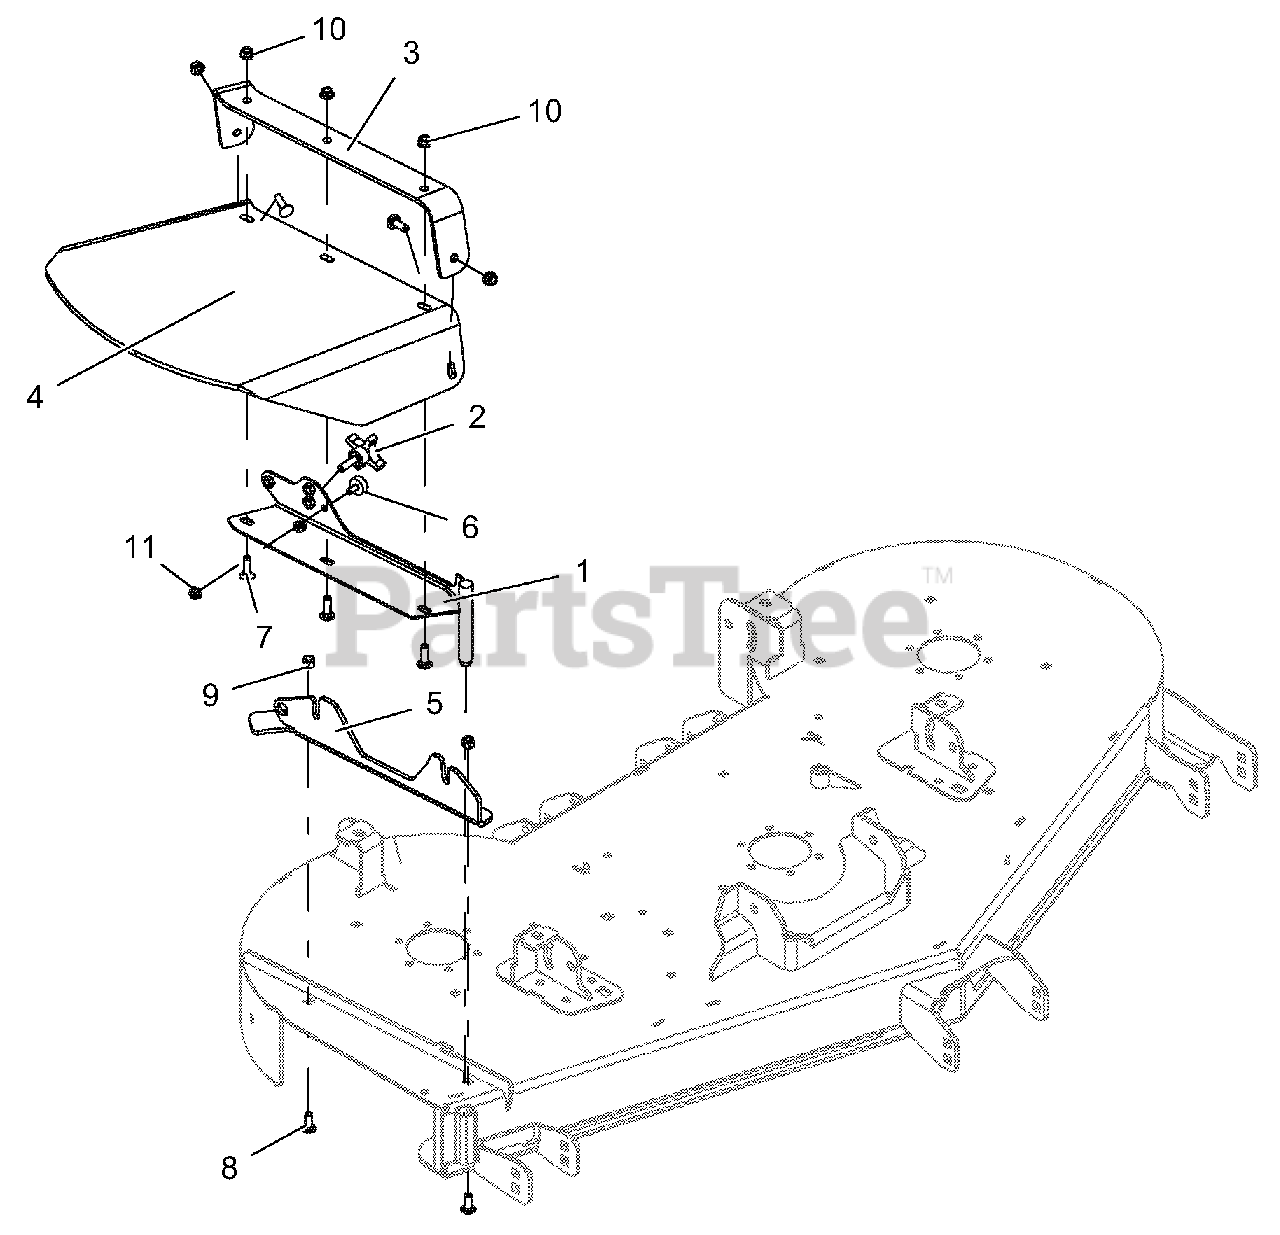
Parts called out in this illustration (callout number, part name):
1	WLDT. DISCHARGE - RED
2	KNOB, 3/8 x 1.25 - 4 PRONG
3	STRAP, WALK RUBBER DISCHARGE - RED
4	SHIELD, WALK RUBBER DISCHARGE
5	DISCHARGE, RUBBER BRKT - RED
6	BUMPER, RUBBER
7	BLT-RDHDSQNK .38-16 x 1.25 G5 YWZC
8	BLT-RDHDSHSQNK .38-16 x 1.0 G5YZ
9	NUT-LK-NYL .38-16 YWZC
10	@NUT-SPNLK-FLG .375-16 YWZC
11	@NUT-SPNLK-FLG .312-18 YWZC
